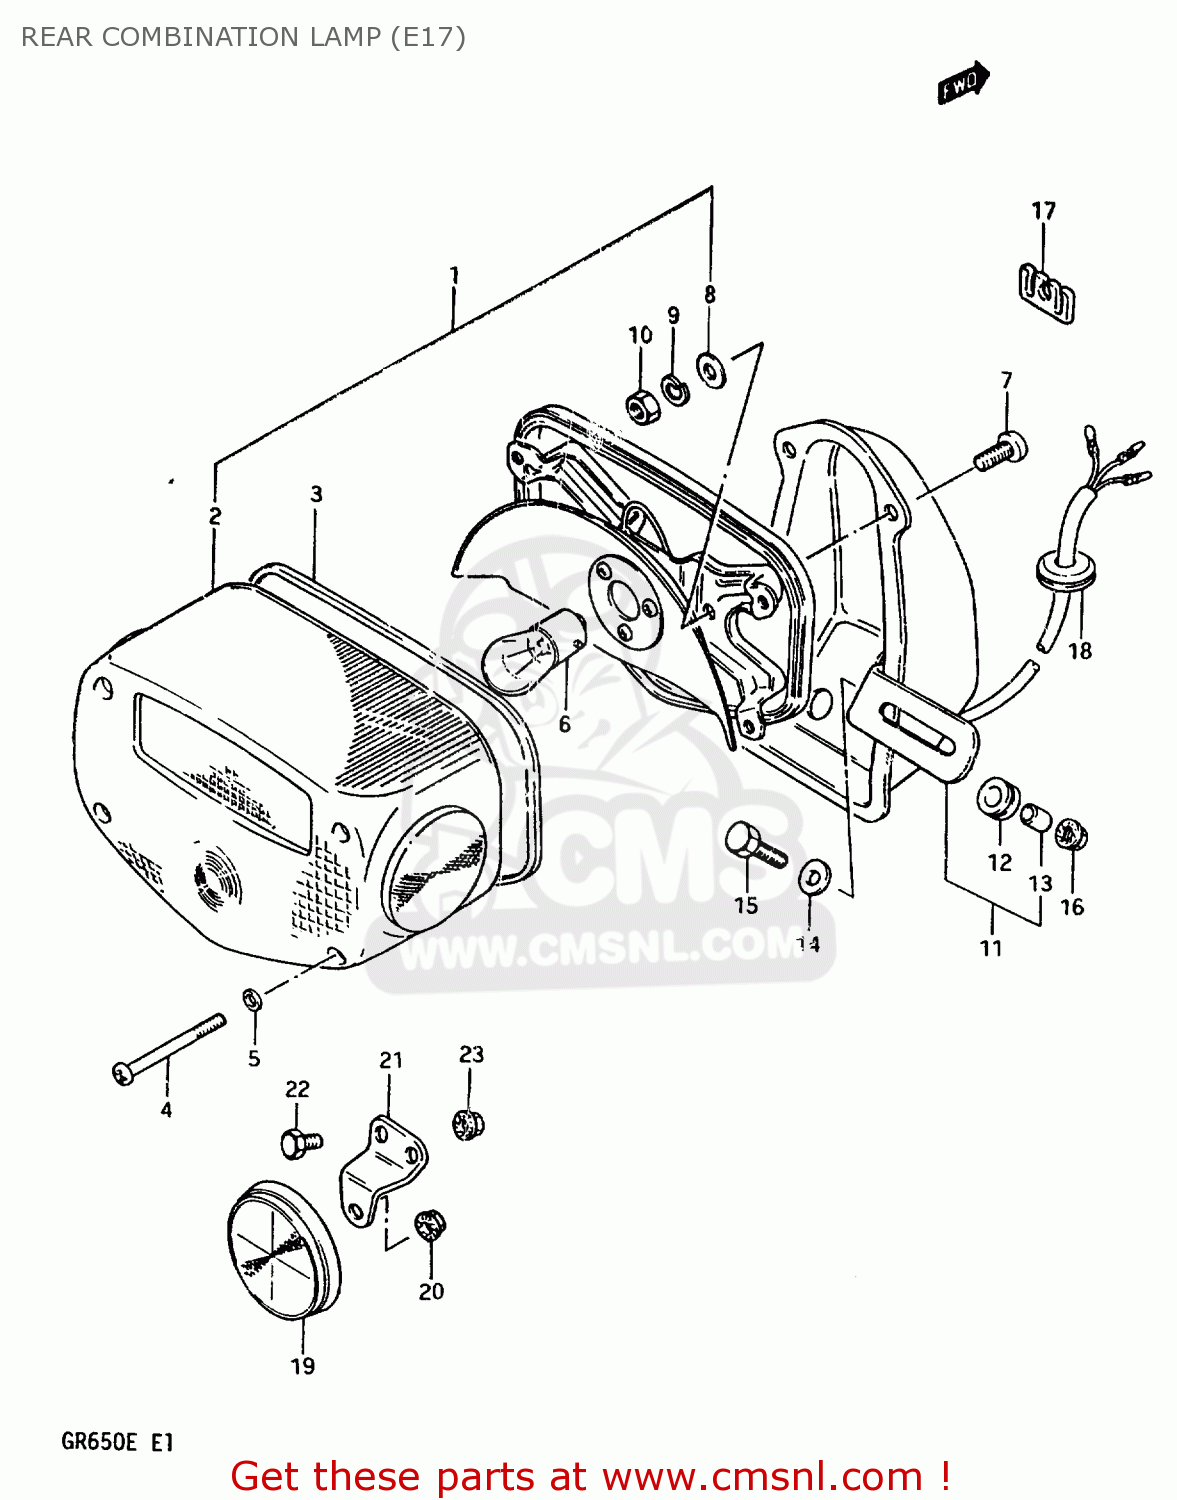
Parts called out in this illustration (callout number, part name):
1	LAMP UNIT, REAR COMBINATION
2	LENS
3	GASKET (NAS)
4	SCREW (4X55)
5	GASKET (NAS)
6	BULB(12V21/5W)
7	SCREW 6X12
8	WASHER
9	LOCK WASHER
10	NUT
11	BRACKET ASSY
12	CUSHION
13	SPACER
14	WASHER (6.5X20X1.2)
15	BOLT
16	NUT 6MM
17	GUIDE,WIRING HARNESS
18	GROMMET
19	REFLEX REFLECTOR,RR
20	NUT 5MM
21	BRACKET, REAR RR.
22	BOLT 5X10
23	NUT 5MM
